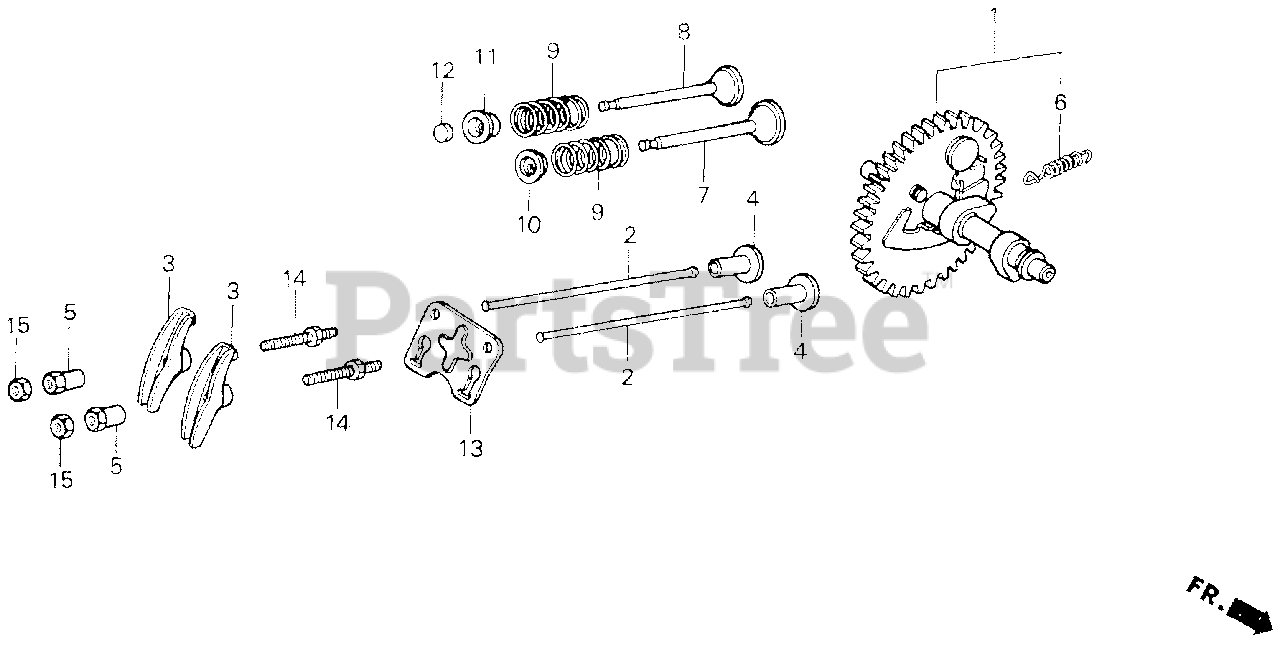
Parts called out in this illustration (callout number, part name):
1	CAMSHAFT ASSY.
2	ROD, PUSH
3	ARM, VALVE ROCKER
4	LIFTER, VALVE
5	PIVOT, ROCKER ARM
6	SPRING, WEIGHT RETURN
7	VALVE, IN.
8	VALVE, EX.
8	VALVE, EX. (STELITE)
9	SPRING, VALVE
10	RETAINER, IN. VALVE SPRING
11	RETAINER, EX. VALVE SPRING
12	ROTATOR, VALVE
13	PLATE, PUSH ROD GUIDE
14	BOLT, PIVOT
14	BOLT, PIVOT (8MM)
15	NUT, PIVOT ADJ.
